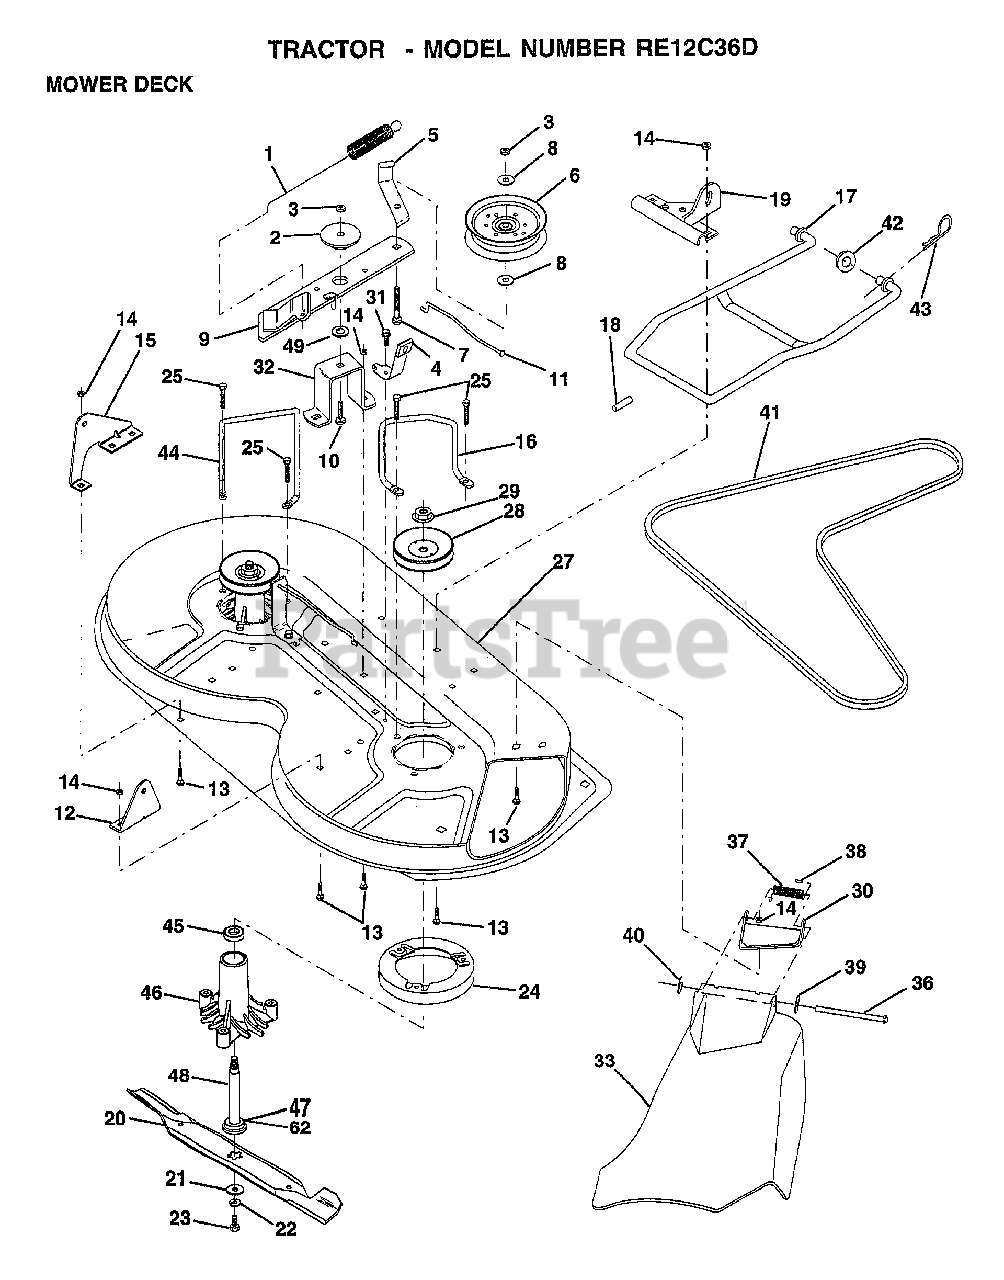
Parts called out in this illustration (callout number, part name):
1	SPRING CLUTCH MWR
2	SPACER.RETAINER.MOWER
4	BRAKE ASM
5	IDLER BELT GUIDE
6	PULLEY IDLER
7	BOLT
8	WASHER
10	BOLT.3/8-14X1.25
11	BRAKE ROD
12	"BRKT,LIFT REAR"
13	BOLT
15	"BRKT,LIFT REAR LH"
16	"KEEPER-BELT,RH"
17	MOWER LINK STAB
18	"PIN,GROOVE"
19	"BRKT,LINK STABILI"
20	"BLADE.36"" HIPERF"
21	WASHER.HARD.BLADE
23	BLADE BOLT
24	STRIPPER RND MWR
25	"SCREW-THD ROLL,WA"
27	"HOUSING-MOWER,36"""
28	PULLEY.MAND.36/46
31	SCREW LT
32	"SUPT,IDLER ARM"
33	SHIELD, DEFLECTOR
36	HINGE ROD
37	SPRING TORSION
38	CAP-SLEEVE LT
39	WASHER
40	NUT PUSH M
41	V-BELT.PRIM.78.5.
43	RETAINER SPRING
44	KEEPER BELT LH
45	BEARING
46	HSG ASM MANDREL
47	BEARING.BALL
49	HARDENED WASHER
62	WASHER.FELT.
